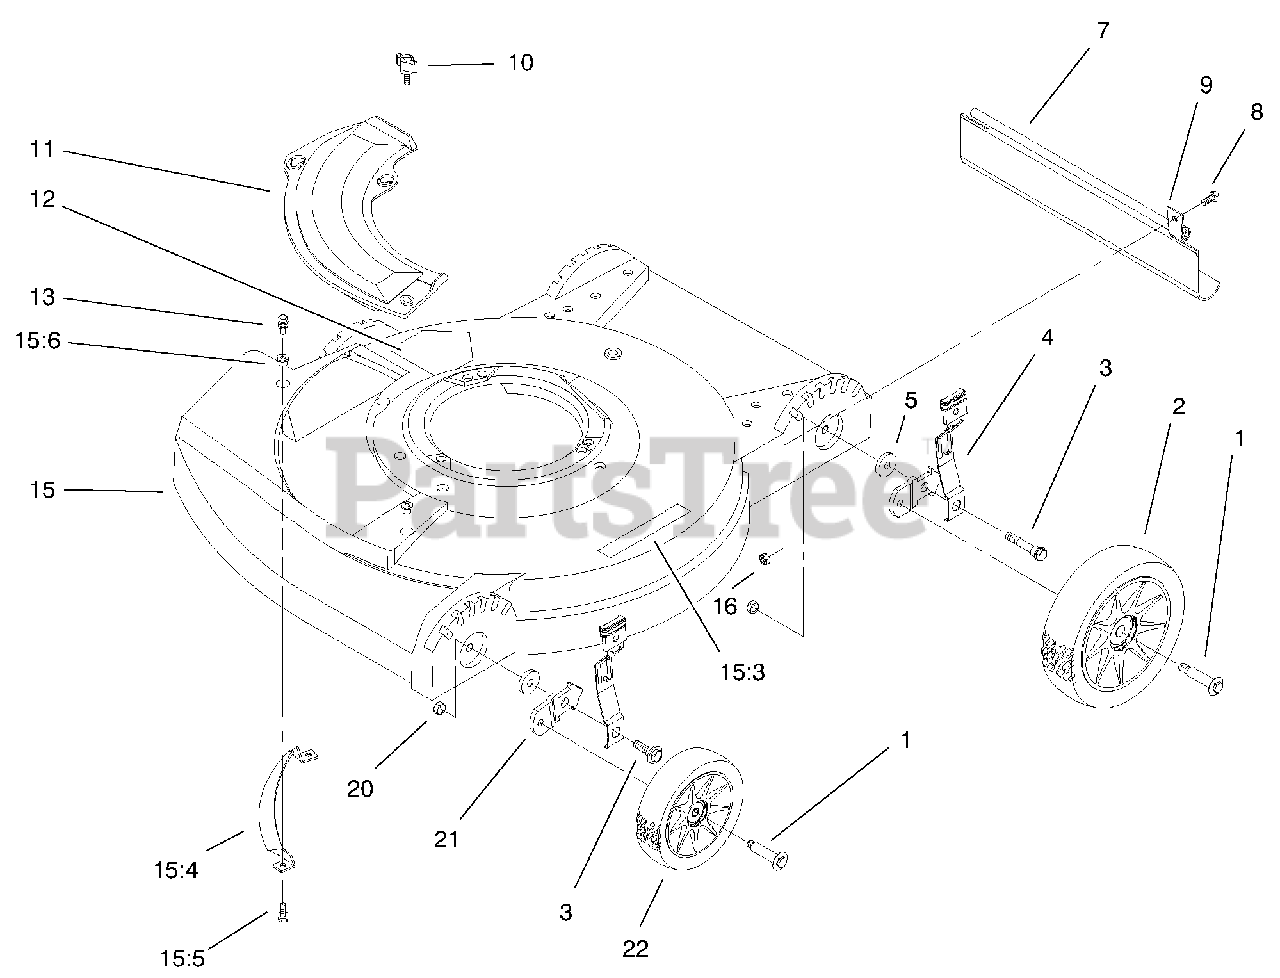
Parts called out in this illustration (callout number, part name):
2	WHEEL/TIRE ASM
4	SPRING ARM ASM
7	SHIELD - TRAILING
8	SCREW-HH
9	CLAMP - SHIELD
11	PLATE-OPENING, CHUTE
13	SCREW-SEMS
15	HOUSING ASM
15:2	DECAL-DANGER
15:3	DECAL-WARNING
15:4	BAR-TOE
15:5	SCREW-HWH
15:6	NUT-CLIP
16	NUT-LOCK, NI
20	NUT-LOCK, NI
21	BRACKET-WHEEL HEIGHT
22	WHEEL/TIRE ASM
